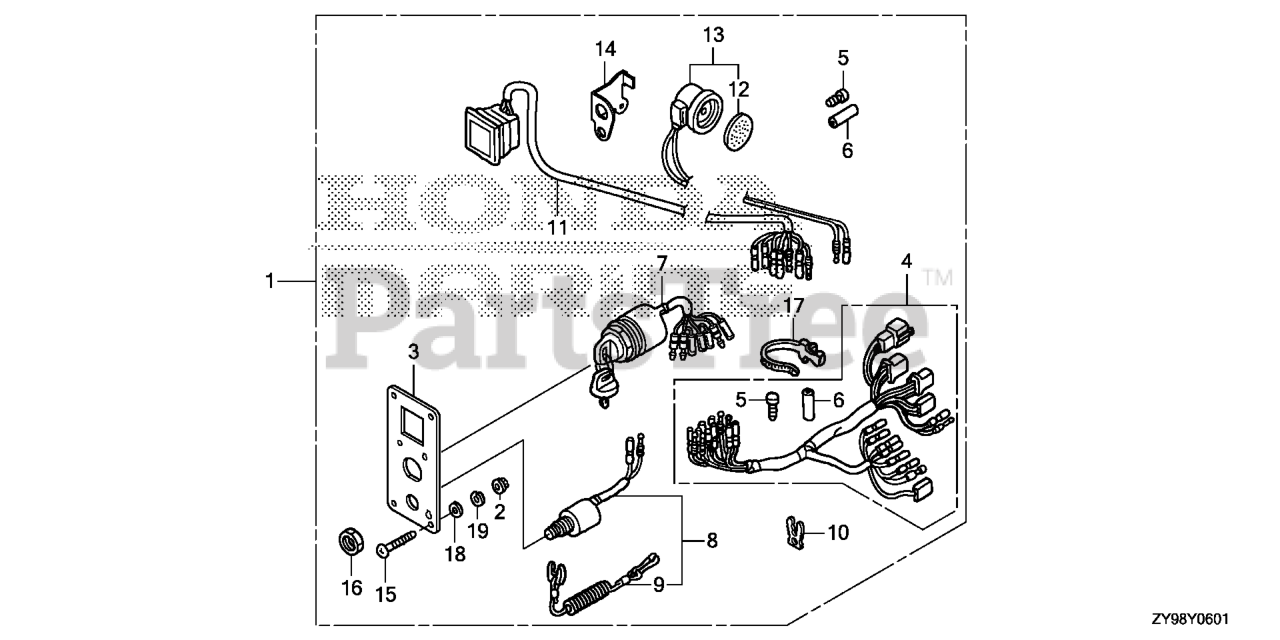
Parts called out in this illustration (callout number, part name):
1	PANEL KIT, SWITCH (4-LED)
2	NUT, FLANGE (5MM) DUAL QTY = (8) (SINGLE)
2	NUT, FLANGE (5MM)
3	PANEL, CONTROL
4	HARNESS ASSY., SWITCH PANEL
5	PLUG, CONNECTOR (INNER) (TROLLING CONTROL)
6	PLUG, CONNECTOR (OUTER) (ENGINE NO.)
7	SWITCH ASSY., COMBINATION (SINGLE) (DUAL)
8	SWITCH ASSY., EMERGENCY STOP
9	WIRE, EMERGENCY (SINGLE) (DUAL)
10	CLIP, EMERGENCY LOCK
11	LAMP ASSY., INDICATION (4-LED)
12	PLATE, TURN SIGNAL BUZZER DUAL QTY = (2) (SINGLE)
13	BUZZER, WARNING DUAL QTY = (2) (SINGLE)
14	BRACKET, BUZZER
15	SCREW, PAN (5X40) DUAL QTY = (8) (SINGLE)
16	NUT, HEX. (16MM) DUAL QTY = (2) (SINGLE)
17	BAND, WIRE HARNESS (150MM) (NATURAL) DUAL QTY = (2) (SINGLE)
18	WASHER, PLAIN (5MM)
18	WASHER, PLAIN (5MM) DUAL QTY = (8) (SINGLE)
19	WASHER, SPG (5MM)
19	WASHER, SPRING (5MM) DUAL QTY = (8) (SINGLE)
